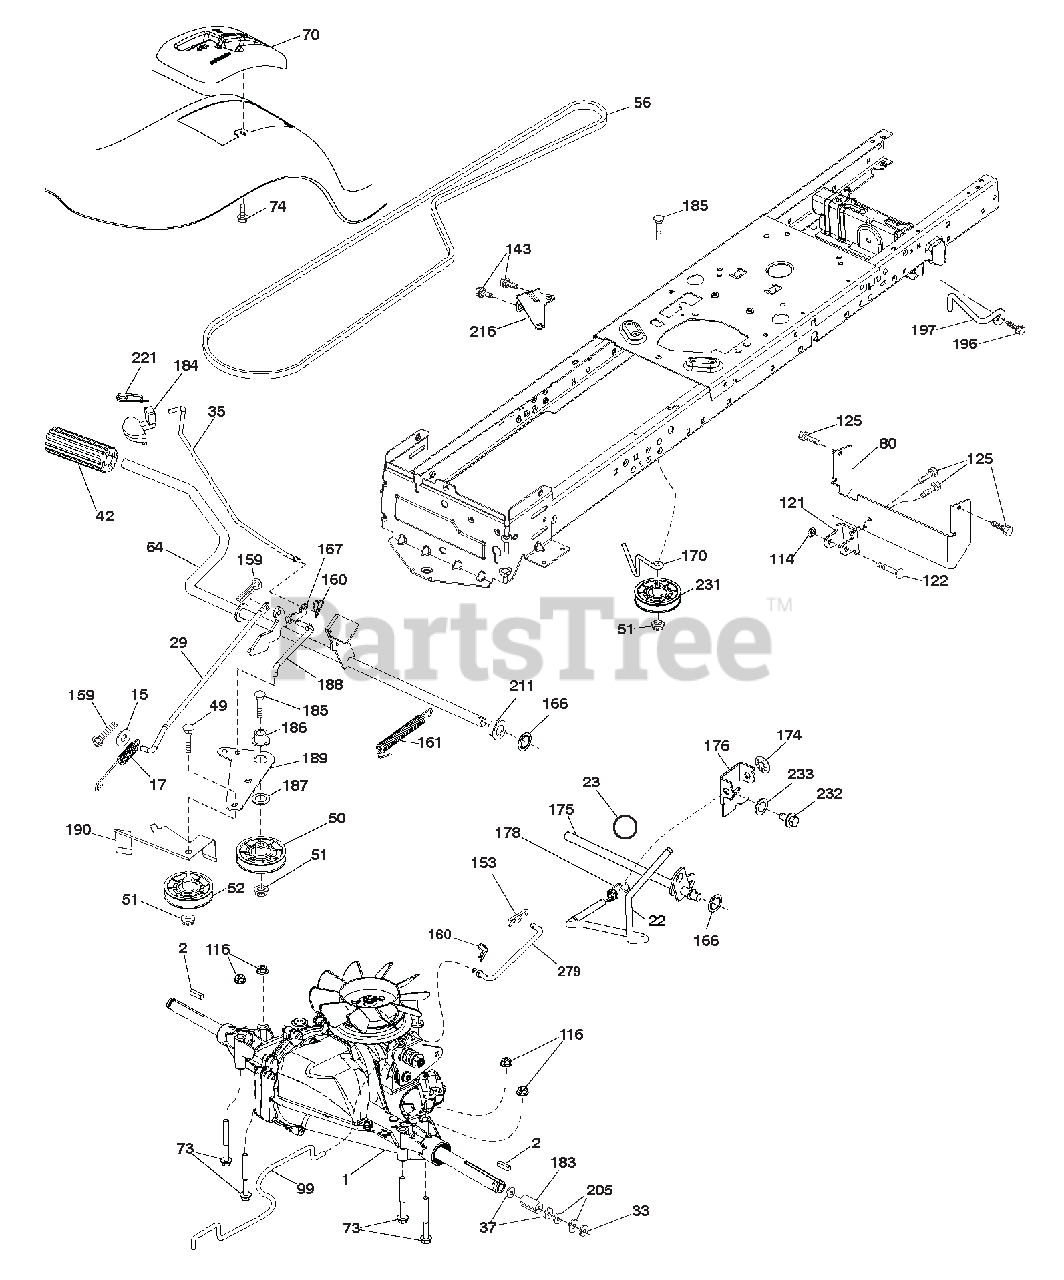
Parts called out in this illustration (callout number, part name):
2	KEY.SQUARE.2.0 X .1845/.1865
15	WASHER.13/32 X 13/16 X 16 GA.
17	SPRING.BRAKE.GT.TEX
22	ROD.SHIFT.FENDER.TLT.2006
23	KNOB DELUXE
29	BRAKE ROD
33	E-RING.#5133-75
35	ROD.BRAKE.PARKING.LT.TEX
37	WASHER.25/32 X 1 1/4 X 16 GA.
42	COVER PEDAL BLK ROUND
49	BOLT.RDHD.3/8-16UNCX1-3/4.GR5
50	IDLER.FLAT.910"OFFSET
51	Nut, Hex, Flangelock 3/8-16
52	IDLER.V-GROOVE.910"OFFSET
56	V-BELT.DRIVE
64	SHAFT ASM.PEDAL.BRAKE CONTROL
70	CONSOLE SHIFT STL HYD BLACK TX
73	BOLT.HEX.FLGHD.5/16-18.GR.5
74	SCREW.HEX.WSH.HI-LO.1/4X1/2UNC
80	STRAP TORQUE
99	ROD.ASM.BYPASS.SPRING.T2.FS
114	Locknut, Washer Insert 5/16-18
116	Nut, Lock Hex Flange 5/16-18 u
121	BRACKET.STRAP.TORQUE.T/A.3500
122	BOLT.5/16-18 x 2.50
125	SCREW.5/16-18X3/4.SMGML.TAP/BL
143	SCREW.THDROL.5/16-18 X 1/2TYTT
153	RETAINER SPRING
159	PIN.COTTER.1/8 X 3/4.CAD.
160	RETAINER.CLIP(M).DIA.290
161	SPRING.RETURN.CLUTCH.6.75
166	NUT PUSH .625
167	LATCH.BRAKE.PARKING
170	KEEPER.CENTER SPAN.1.688
174	NUT.PUSH..500
175	SHAFT ASM.SHIFT.T2/K66.FS.TX
176	ARM.CLEVIS.ROD.SHIFT
178	SPRING.SHIFT.GT.2006
183	SPACER.AXLE.PVST
184	HANDLE.PARKNG.BRAKE.LT.TEX.667
185	BOLT.RDHD.3/8-16UNC X2-3/4 GR5
186	SPACER.RETAINER
187	WASHER.13/32 X 2 X 10 GA.
188	LINK.CLUTCH.GROUND DRIVE
189	BELLCRANK.GROUNDRIVE.NSTG/NSTL
190	KEEPER.BELLCRANK.DRIVE.GROUND
196	SCREW.3/8-16X1.SMGML.TAP/R.BLK
197	LINK.CLUTCH.ANTI-ROTATIN.1"CRK
205	WASHER.25/32 X 1-5/8 X 16GA.
211	BUSHING.SHAFT.BRAKE.HAND CONTR
216	BRACKET.PULLEY.IDLER.WTEX
221	RETAINER.SPRING.CLIP.HANDLE
231	IDLER.V-GROOVE.1.688"OFFSET
232	BOLT.FIN HEX.7/16-14X1 GR5
233	WASHER.SERRATED
279	LINK SHAFT
